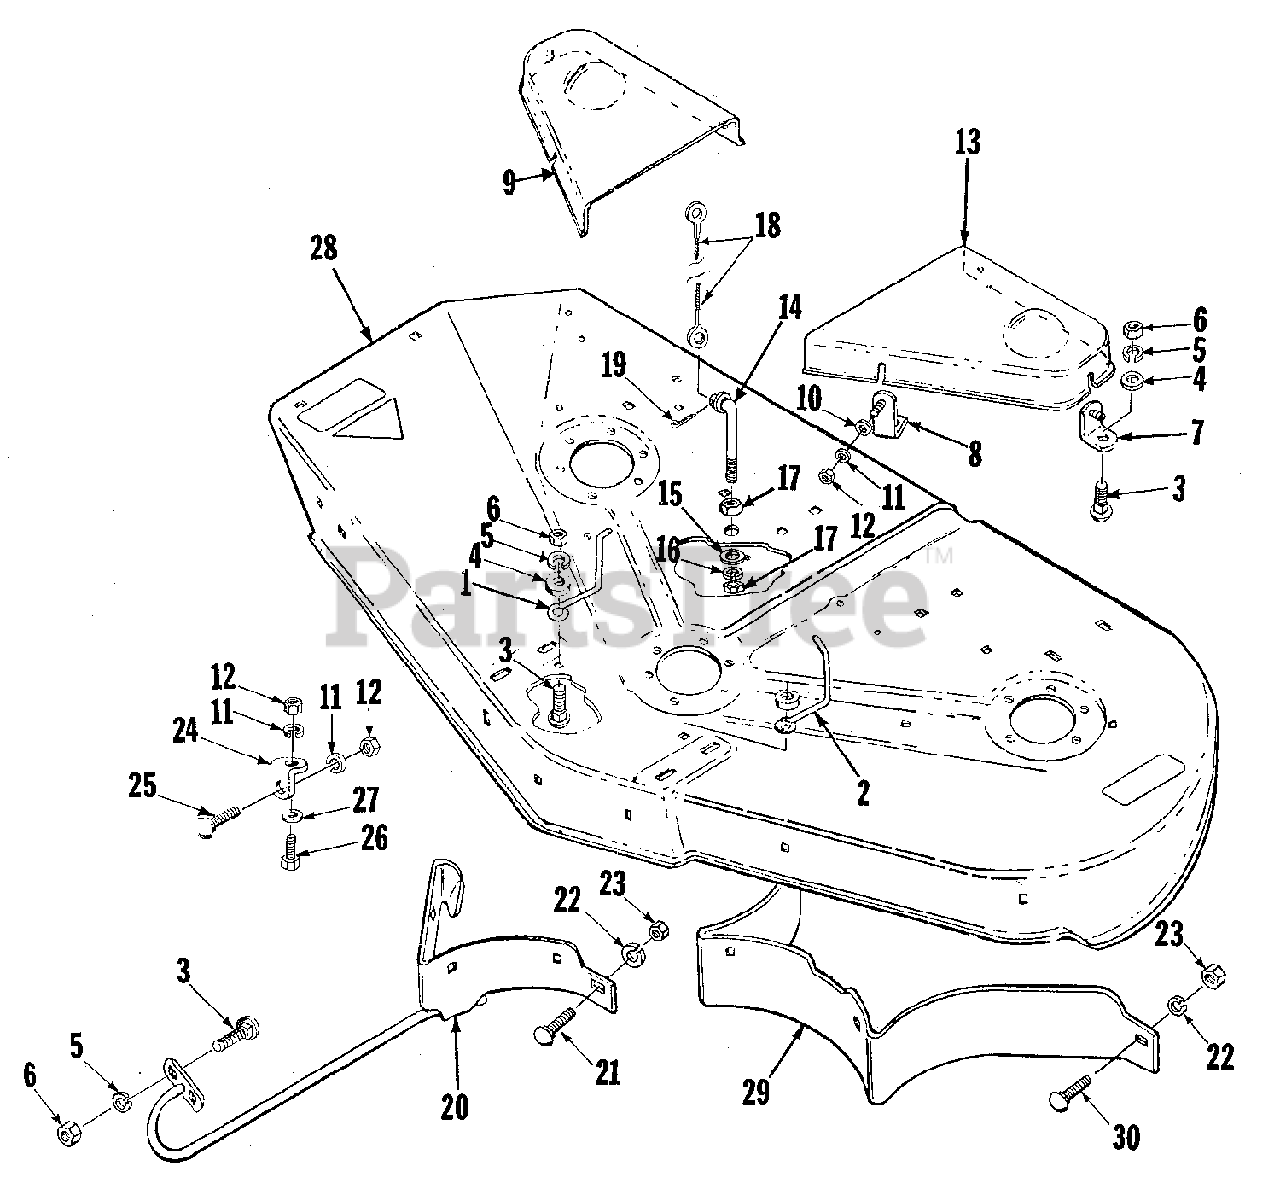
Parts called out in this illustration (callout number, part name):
1	GUIDE, Belt (R.H.)
2	GUIDE, Belt (L.H.)
3	BOLT, Round Head, 5/16-18 x 3/4
4	WASHER, Flat, 5/16
5	WASHER, Lock
6	NUT, Hex, 5/16 x 18
7	LEG ASSEMBLY, Arbor Cover (Outer)
8	LEG ASSEMBLY, Arbor Cover (Inner)
9	COVER, Arbor (R.H.)
10	WASHER, Flat
11	WASHER, Lock
13	COVER, Arbor (L.H.)
14	HOOK, Mower Lift
15	WASHER, Flat
16	WASHER, Lock
18	CABLE ASSEMBLY, Lift
20	GUARD ASSEMBLY, Discharge
21	BOLT, Round Head
22	WASHER, Lock
24	CLIP, Baffle
25	BOLT, Round Head
26	SCREW, Hex Head Cap
27	WASHER, Flat
28	HOUSING, Mower (42")
28	HOUSING, Mower (48")
29	BAFFLE, Mower (42")
29	BAFFLE, Mower (48")
30	BOLT, Round Head, 3/8-16 x 1
30	BOLT, Round Head
